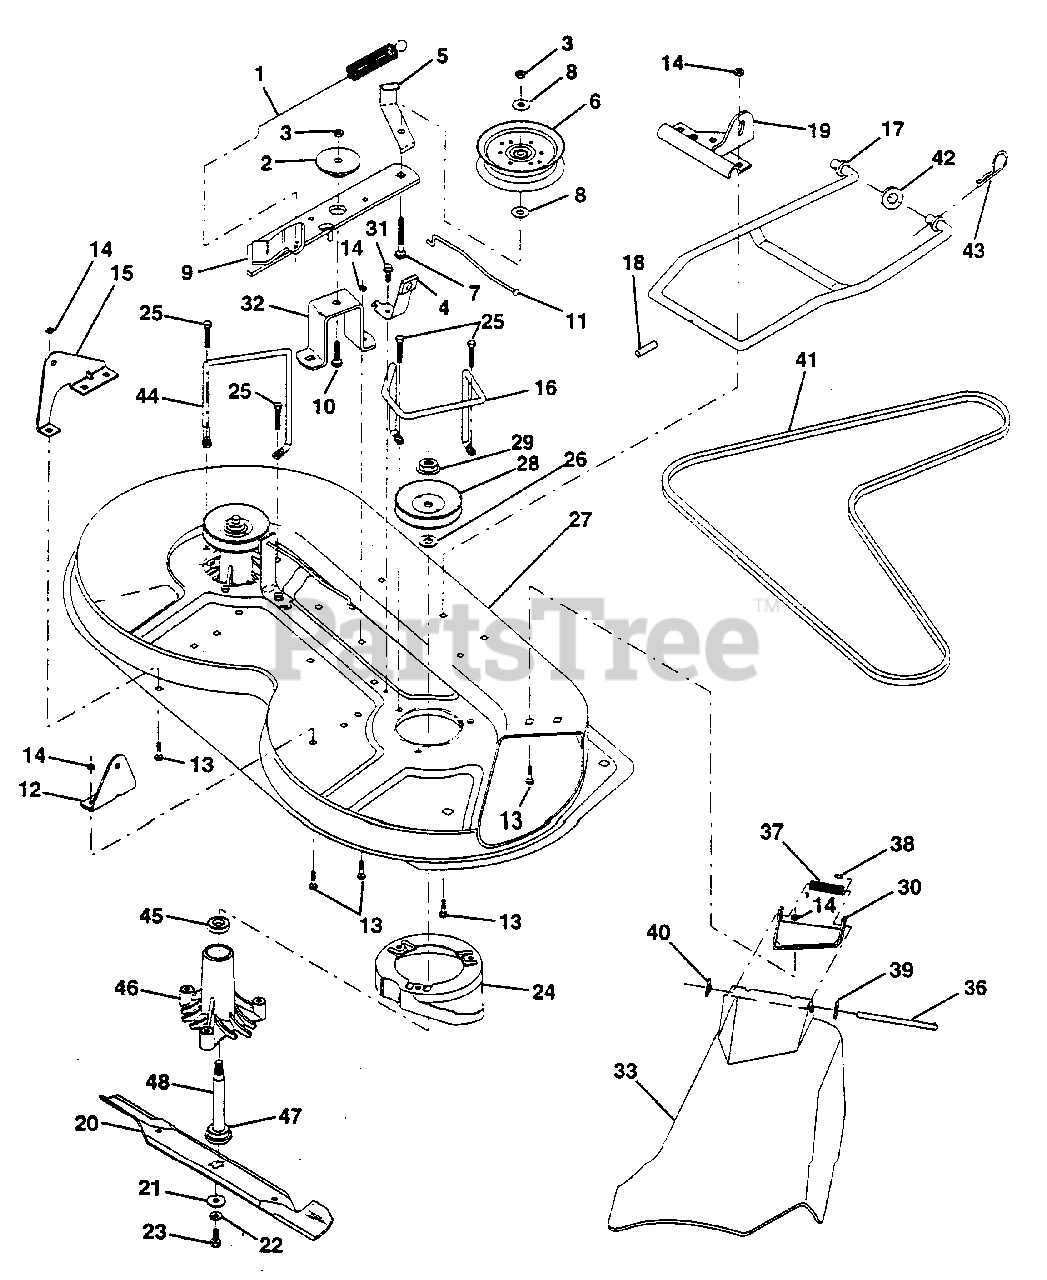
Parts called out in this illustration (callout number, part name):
1	Spring, Mower Clutch (AYP part number)
2	Spacer, Retainer (AYP part number)
3	Nut, Crownlock
4	Brake Asm. (AYP part number)
5	Guide, Belt Idler (AYP part number)
6	Pulley, Flat Idler (AYP part number)
7	Bolt, Carr. 3/8-16 x 2 (AYP part number)
8	Washer 13/21 x 7/8 x 10 Ga. (AYP part number)
9	Arm Asm., Idler Mower (AYP part number)
10	Bolt, Carriage 3/8-16 x 1 (AYP part number)
11	Rod, Brake (AYP part number)
12	Bracket, Lift R. H. Rear
13	Bolt, Carriage 5/16-18 x 5/8 (AYP part number)
14	Nut, Crownlock 5/16-18
15	Bracket, Lift L. H. Rear
16	Keeper, R. H. (AYP part number)
17	Link, Asm. Mower Stabilizer
18	Pin, Drive (AYP part number)
19	Bracket, Asm. Front (AYP part number)
21	Washer, Hard (AYP part number)
22	Washer, Lock 3/8 (AYP part number)
23	Bolt 3/8-24 x 1-1/4 Gr. 8 (AYP part number)
24	Stripper (AYP part number)
25	Bolt 5/16-18 x 1-1/4 (AYP part number)
26	Washer .150 Thk. (AYP part number)
27	Deck Assembly
28	Pulley, Mandrell (AYP part number)
29	Nut, Flangelock 9/16 (AYP part number)
30	Bracket, Asm. Deflector (AYP part number)
31	Screw, Hex Wsh. Thdrol. 5/16-18 x 1/2 (AYP part number)
32	Arm, Support Idler Mower (AYP part number)
33	Deflector (AYP part number)
36	Rod, Hinge (AYP part number)
37	Spring, Torsion Deflector (AYP part number)
38	Cap, Sleeve (AYP part number)
39	Washer 11/32 x 5/8 x 16 Ga. (AYP part number)
40	Pushnut (AYP part number)
42	Washer 11/32 x 5/8 16 Ga. (AYP part number)
43	Retainer, Spring (AYP part number)
44	Keeper, L. H. (AYP part number)
45	Bearing (AYP part number)
46	Housing Mandrel Vented
47	Bearing (AYP part number)
48	Shaft, Mandrel (Inc. 47)
